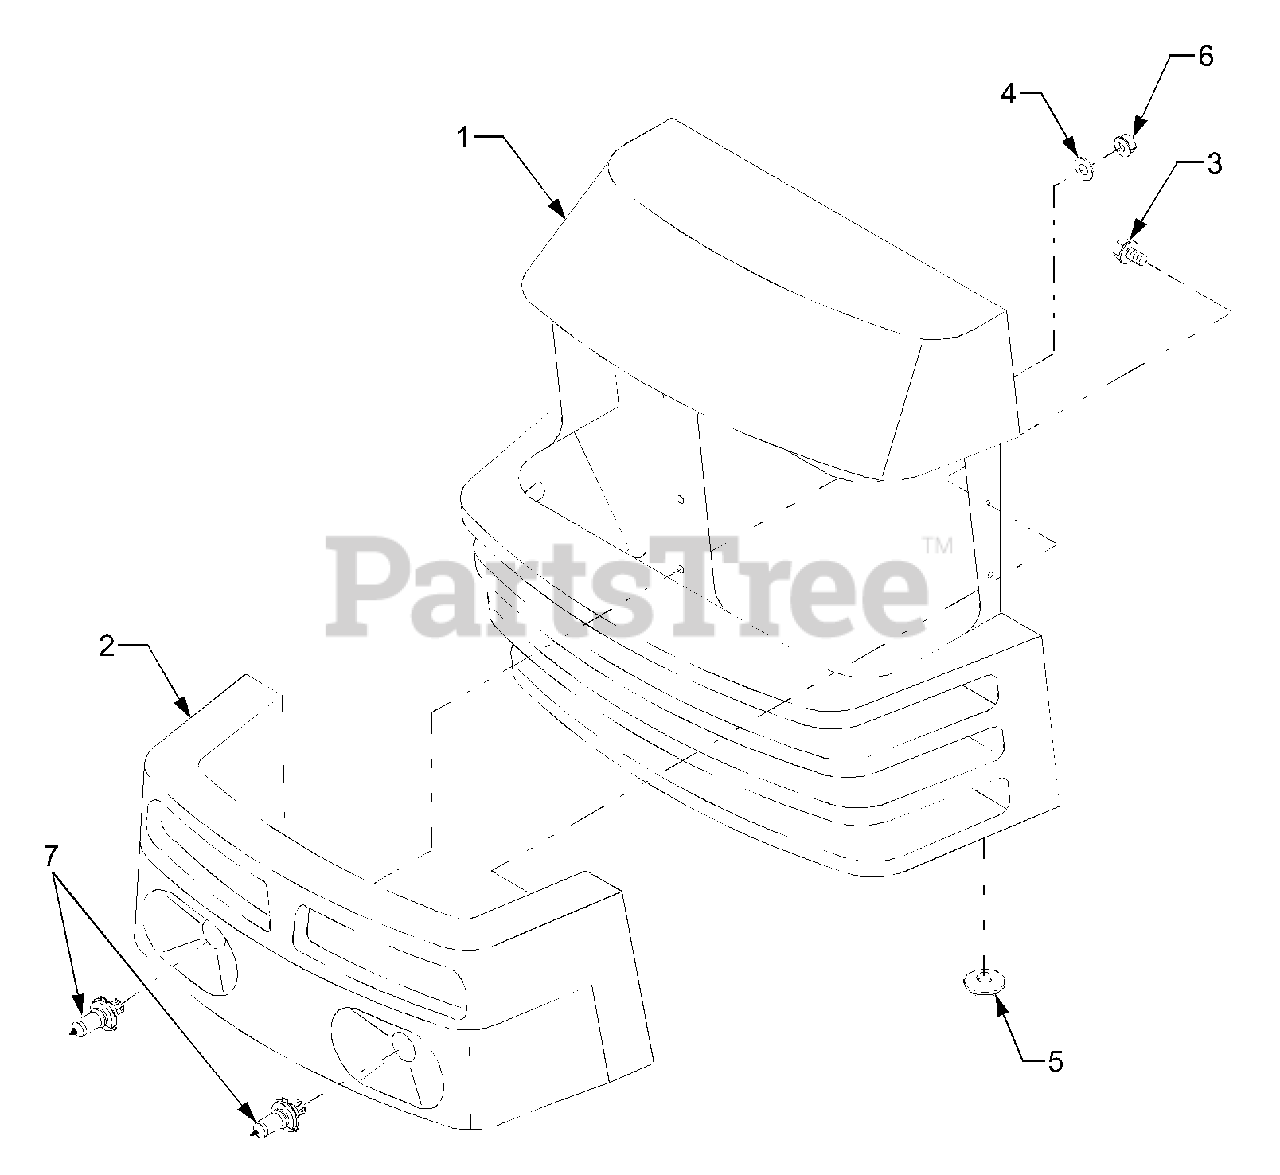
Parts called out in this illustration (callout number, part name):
1	Front Grill Ass'y
2	Head Lamp Ass'y
4	Washer, Plain
5	Rubber, Cushion
